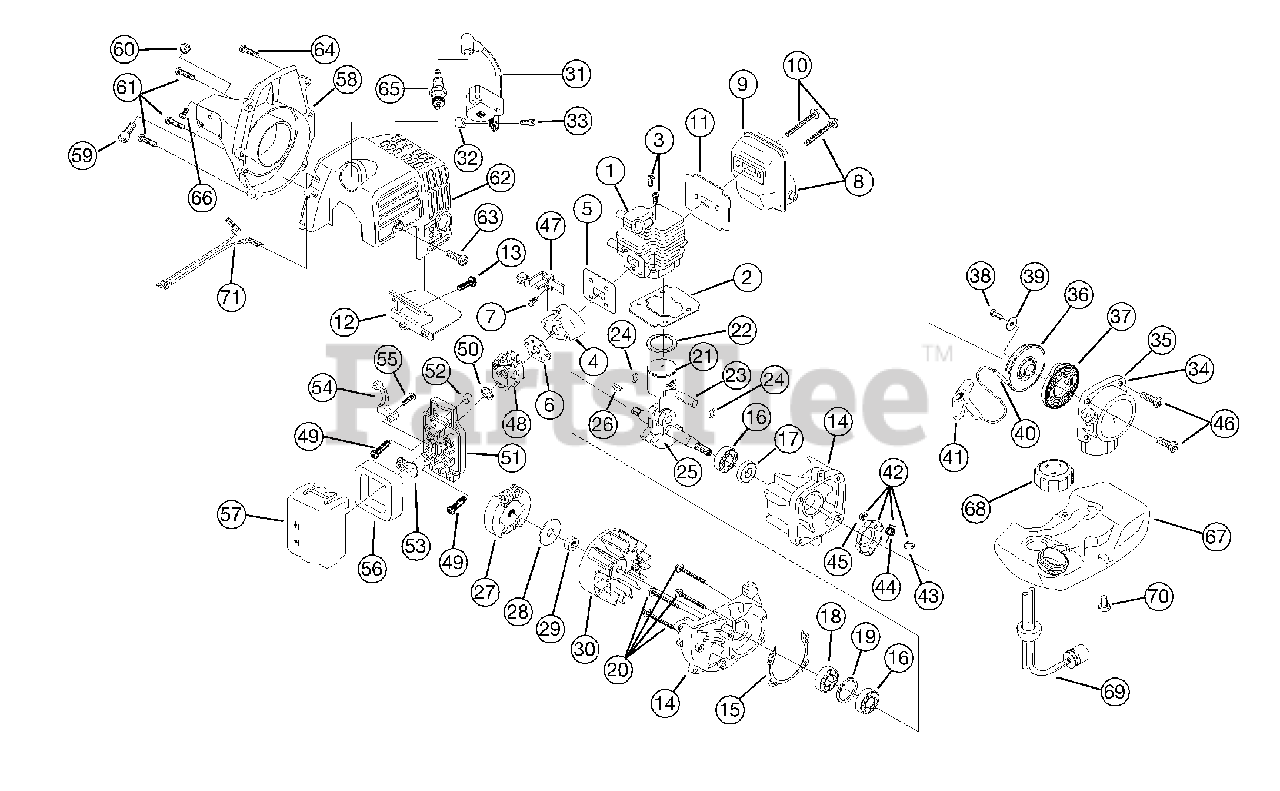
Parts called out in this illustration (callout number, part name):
1	Cylinder
2	Cylinder Base Gasket
4	Insulator
5	Insulator Gasket
6	Carburetor Gasket
7	Screw and Washer
8	Muffler Assembly
9	Muffler
11	Muffler Gasket
12	Muffler Plate
14	Crankcase Service Assembly
15	Crankcase Gasket
19	Snap Ring
25	Crankshaft
28	Clutch Washer
30	Flywheel Assembly
31	Module Assembly
34	Recoil Assembly
35	Recoil Case
36	Recoil Pulley
37	Recoil Spring
41	Pull Handle
42	Pulley Assembly
43	Ratchet
45	Retaining Ring
47	Throttle Bracket
48	Carburetor
51	Air Cleaner Assembly
53	Choke Plate
54	Choke Lever
57	Air Cleaner Cover
58	Clutch Housing Assembly
62	Engine Cover
67	Fuel Tank
68	Fuel Cap Assembly
69	Fuel Line Assembly
71	Lead Wire Assembly
